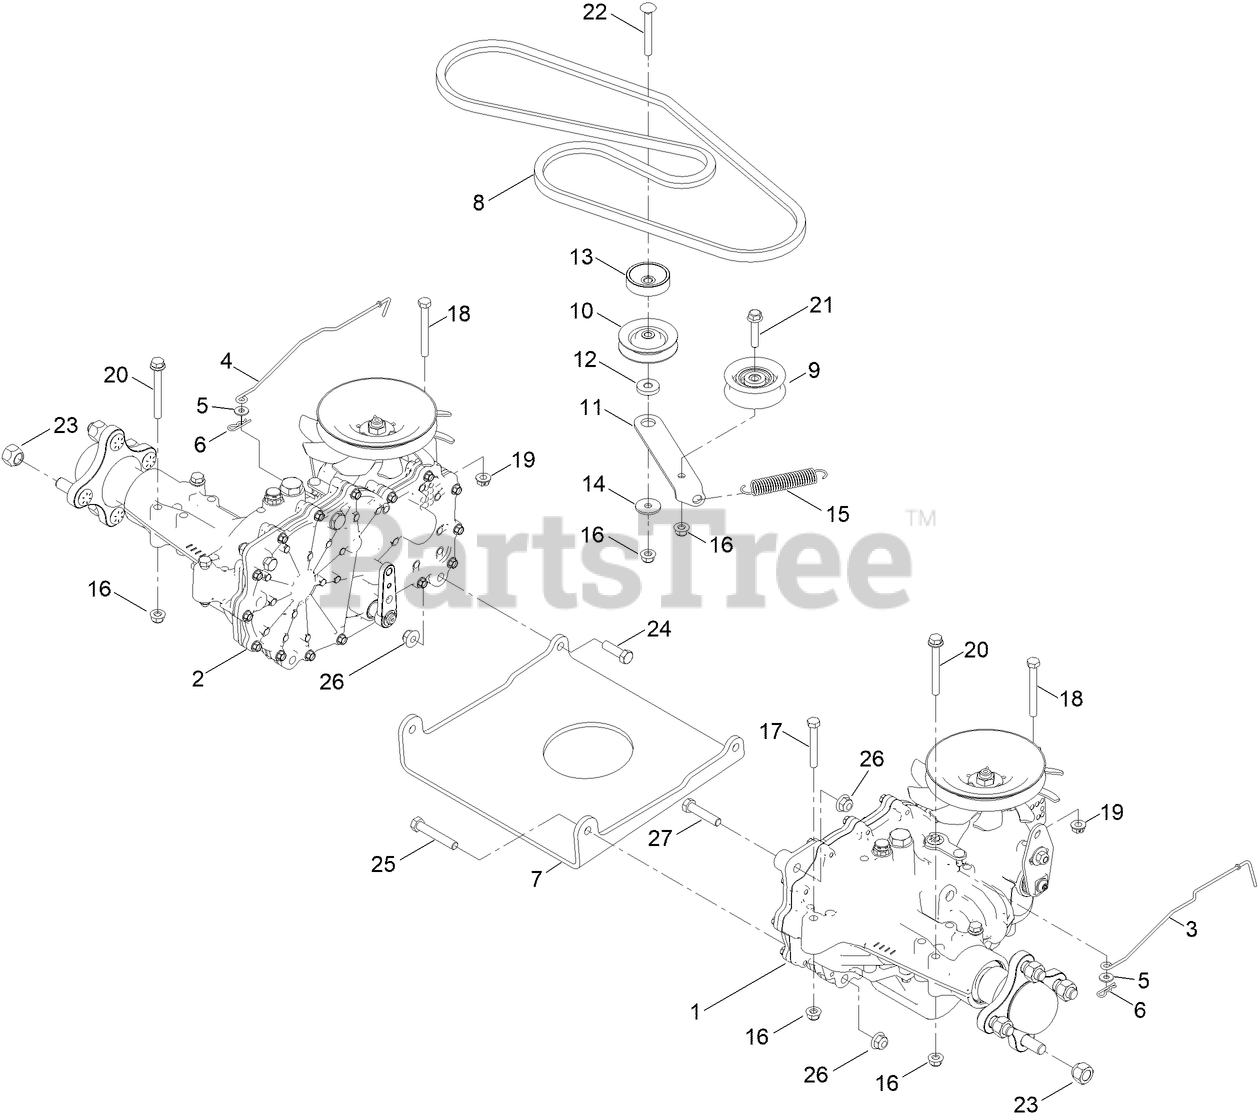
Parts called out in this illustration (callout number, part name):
1	RH HYDRO TRANSMISSION ASM
2	LH HYDRO TRANSMISSION ASM
3	ROD-BYPASS, LH
4	ROD-BYPASS, RH
5	WASHER
7	PLATE-HYDRO
8	V-BELT (A SEC 65.30 EL)
9	PULLEY-IDLER, FLAT
11	ARM-IDLER
12	SPACER-IDLER ARM
13	SPACER
14	WASHER-PIVOT
15	SPRING-PEDAL, RETURN
16	NUT-HF, NI
17	SCREW-HH
18	SCREW-HH SPCL
19	NUT-HF
20	SCREW-HHF
21	SCREW-HHF
22	SCREW-CARR
23	NUT-LUG
24	SCREW-HH
25	SCREW-HH
26	NUT-HF, NI
27	SCREW-HH
